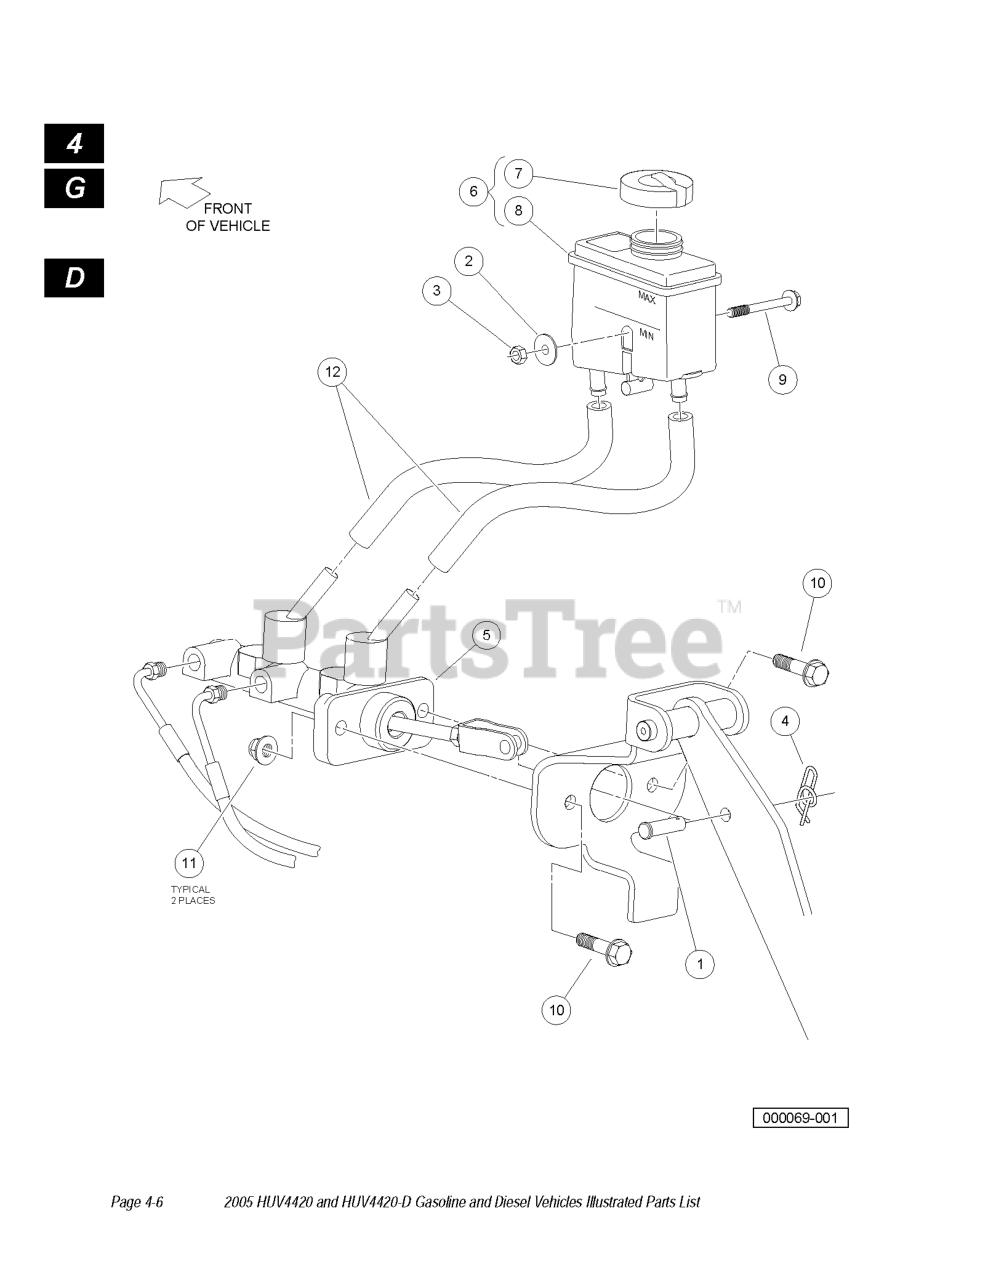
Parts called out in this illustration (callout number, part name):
1	CLEVIS PIN, 5/16 X 1
3	LOCKNUT, M6-1.00 NYLON INSERT
5	CYLINDR, MASTER, TANDEM
6	ASM, RESERVOIR, REMOTE, MC
7	FILLER CAP ASM
9	BOLT-M6X1.0X65 HEX FL HD, BLK
10	BOLT FLG, M8X1.25X35
11	LOCK NUT, FLG M8 X 1.25 NYLON
12	LINE, RESERVOIR, BRAKE
